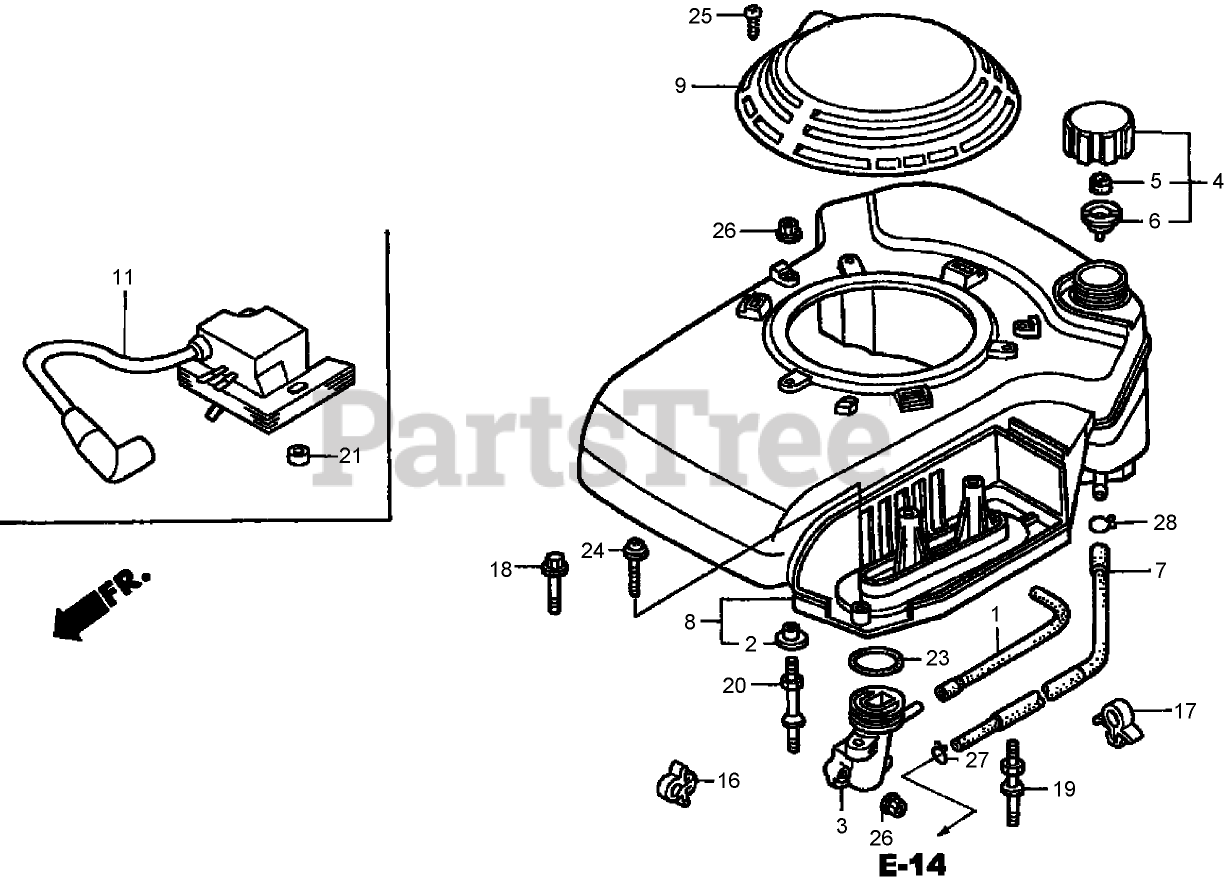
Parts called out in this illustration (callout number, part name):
1	Tube-Breather
2	COLLAR-CLEANER, AIR
3	ELBOW-CLEANER, AIR
4	FUEL TANK CAP ASM
5	Sponge-BREATHER, Fuel Cap
6	GASKET-CAP, FUEL
7	FUEL TANK TUBE ASM
8	Cover-Fan
9	HOOD-COVER, FAN
11	Ignition Coil ASM
16	HOLDER-WIRE, STOP SWITCH
17	CLAMP-PIPE, BRAKE
18	BOLT-FLANGE (6X28) (C T200) (engine serial numbers starting at 6901761)
19	Bolt-Stud
20	BOLT-STUD
21	Collar-Special
23	O-Ring (33.3X3.5)
24	SCREW-WASHER (6X35)
25	Screw-Tapping (4X20)
26	NUT-FLANGE (6 mm)
27	CLIP-TUBE (B8)
28	CLIP-TUBE (C9)
